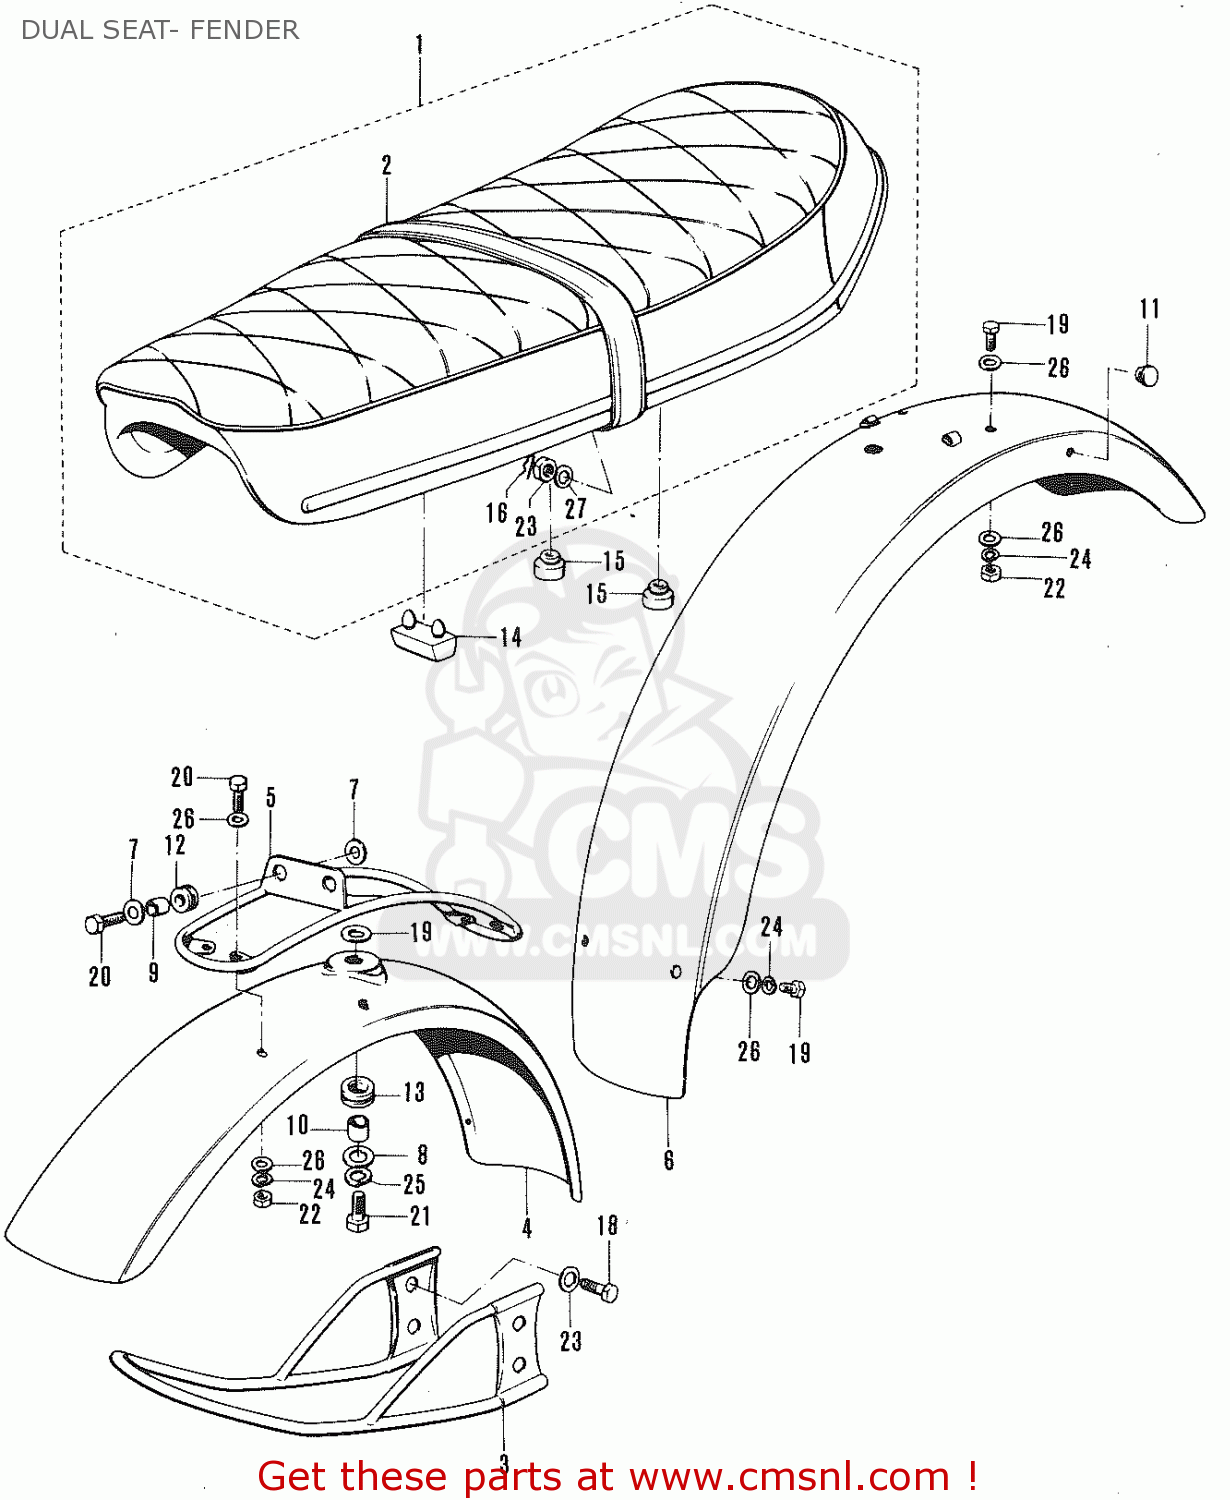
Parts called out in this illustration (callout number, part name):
1	SEAT ASSEMBLY
2	BAND,SEAT
3	FRONT GRAB BAR
4	FENDER,FRONT
5	BRACE,FRONT FENDER
6	FENDER,REAR
7	WASHER (6.5X20X1.2)
8	WASHER
9	SPACER (7X9X7)
10	SPACER(8.2X10X8)
11	PLUG
12	CUSHION
13	CUSHION
14	CUSHION
15	CUSHION
16	CLIP
17	HEXAGON BOLT
18	HEXAGON BOLT
19	BOLT
20	HEXAGON BOLT
21	BOLT
22	NUT
23	NUT
24	LOCK WASHER
25	LOCK WASHER
26	WASHER
27	WASHER
